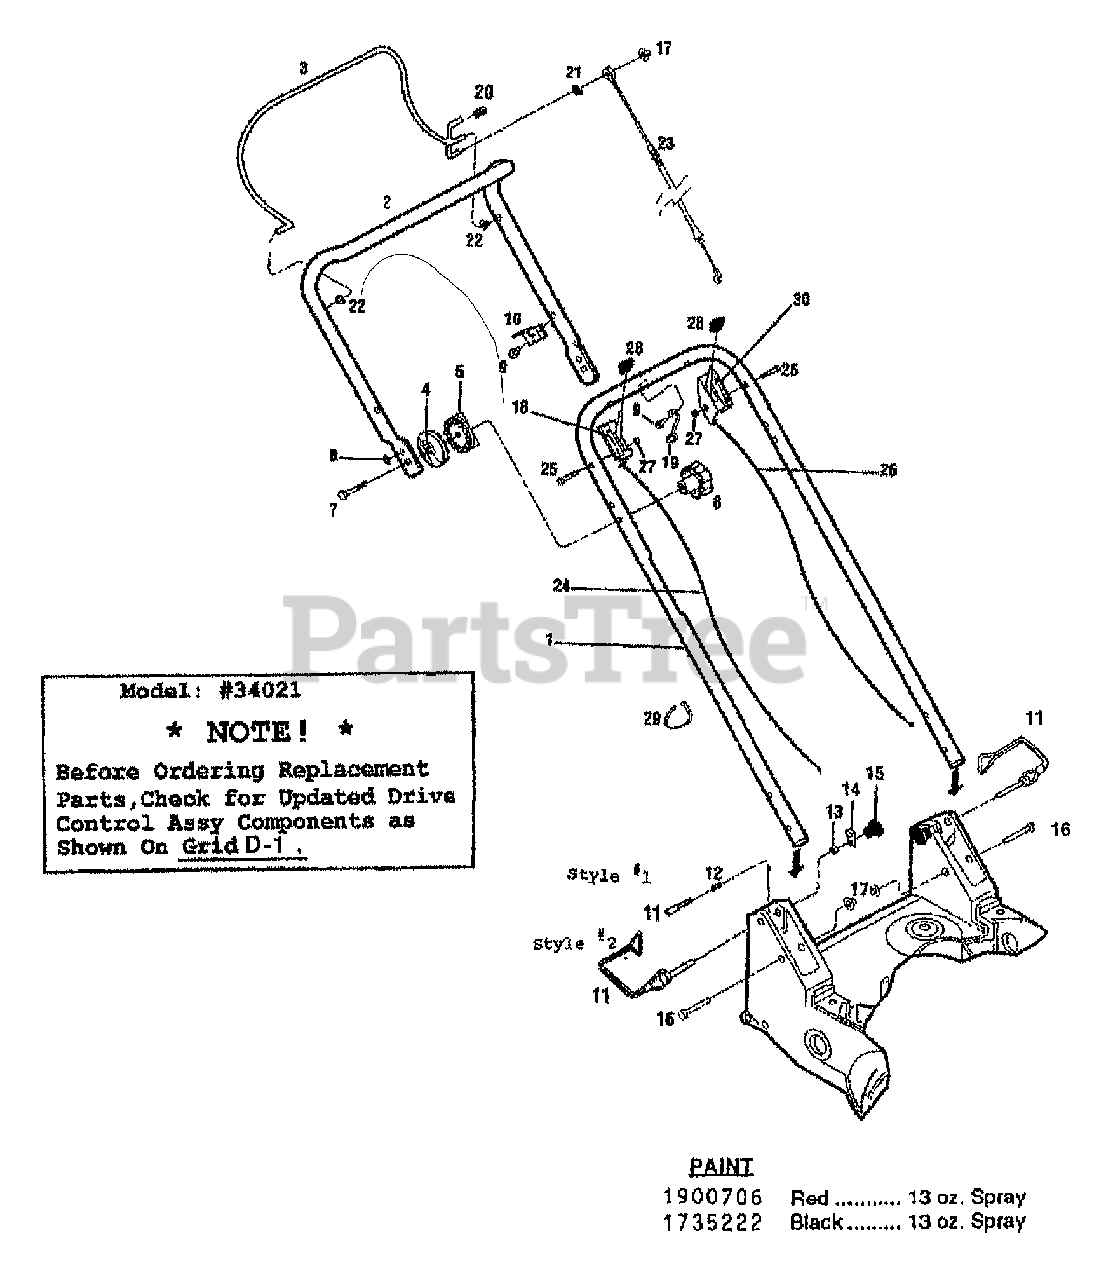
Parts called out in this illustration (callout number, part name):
1	HANDLEBAR-LOWER
1	HANDLEBAR-LOWER PNT (34021-0400101-0599999)
2	HANDLEBAR-UPR PNT
3	BAIL-CONTROL VINYL COATED
4	QUADRANT-OUTER (WAS 1767425)
5	KIT-QUADRANT INNER (WAS 1767375)
7	SCR-CURVED HD 5/16-18X2.0 (WAS 1767448)
8	RETAINER .25
9	SCR-FLANGE 1/4-20X3/4 GR5
11	PIN-LK SQ. #W51620LP (34021-0400101-0599999)
11	PIN-STOP
12	SPRING-COMPRESSION
13	NUT-HEX 1/4-20 ZP
14	ARM-STOP ZP BLACK CHRMATE
15	KNOB
16	PIN-CLEVIS ( @DEPL)
17	CAP-PUSH .312
18	DECAL-ENGINE SPEED
19	GUIDE-ROPE
20	HANDLE GRIP
21	GRIP-RING EXT .312 ID
22	BUSHING-PLASTIC (BAIL)
23	CABLE-ENGINE BRAKE
24	CONTROL-THROTTLE
25	SCR-HH 1/4-20X1.75 G5 ZP {34020, 34021}
26	CONTROL-CLUTCH {34021}
27	NUT-HT LK 1/4-20 {34020, 34021}
28	KNOB-WHEEL DRIVE CABLE {34020, 34021}
29	TIE-CABLE {34020, 34021} REUSABLE
30	DECAL-WHEEL DRIVE {34021}
